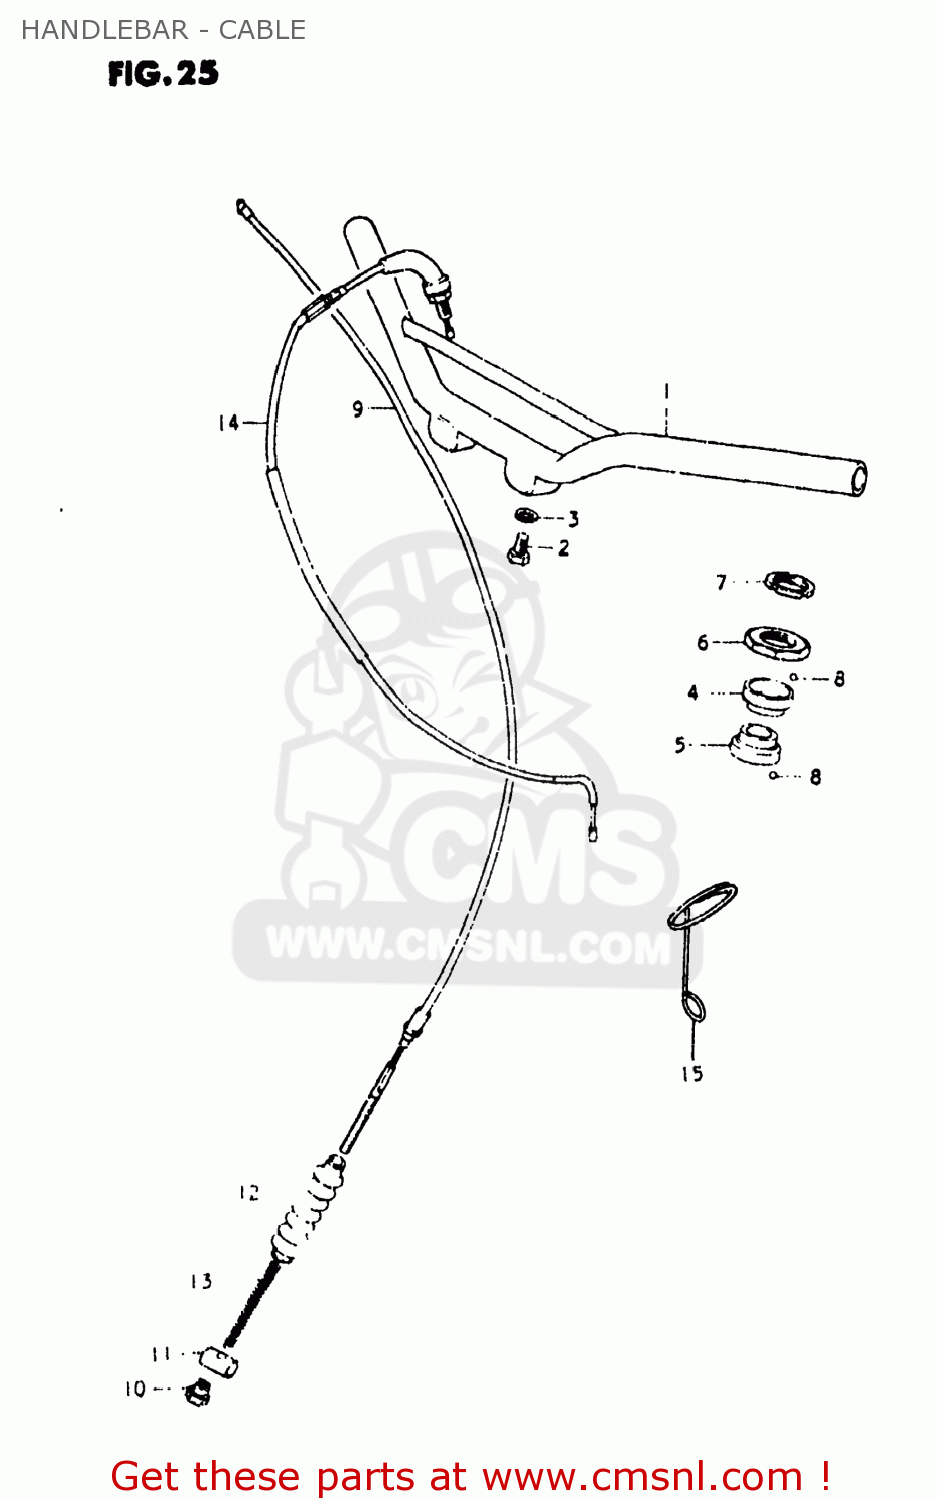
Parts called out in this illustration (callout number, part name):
1	HANDLEBAR
2	BOLT
3	LOCK WASHER
4	RACE,STEERING,INNER,UPPER
5	RACE,STEERING,INNER,LOWER
6	RACE,STEERING,OUTER,UPPER
7	NUT,STEERING STEM
8	BALL
9	CABLE ASSEMBLY,FRONT BRAKE
10	NUT
11	PIN,10X19
12	SEAL,DUST(7X16X75)
13	SPRING
14	CABLE ASSEMBLY,THROTTLE
15	CLIP
